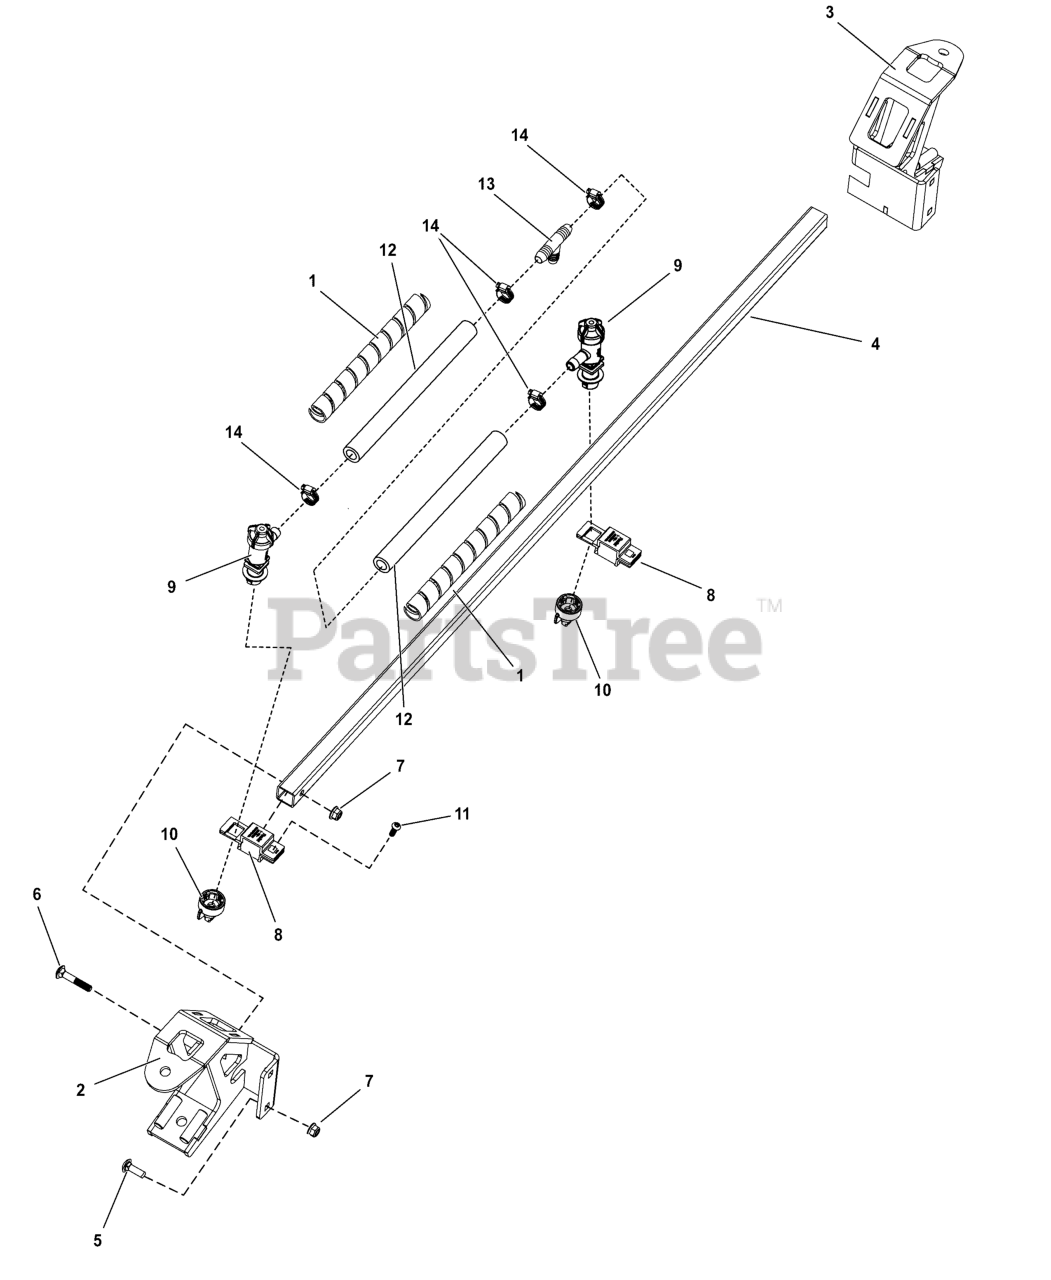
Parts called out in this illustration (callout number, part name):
1	WRAP, HOSE, .813" ID X 9.0"
2	WELD, LFT BOOM PIVOT
3	WELD, RT BOOM PIVOT
4	TUBE, SPRAY BOOM CENTER
5	BLT-RDHDSQNK, .3125"-18 X 1.000" SS188
6	BLT-RDHDSQNK, .3125"-18X1.750" SS188
7	NUT-HEX-NYLK, FLG .3125"-18 SS188
8	CLAMP, NOZZLE QJ111SQ-1-304SS
9	BODY, NOZZLE QJ300
10	TIP, NOZZLE AIXR 110025 VIOLET
11	SCR-CAP, SBH .250-20 X .750" SS188
12	HOSE, CHEM .50" X 9"
13	FITTING, TEE, 1/2" MPT
14	CLAMP, MINIATURE WORM GEAR MAH6
